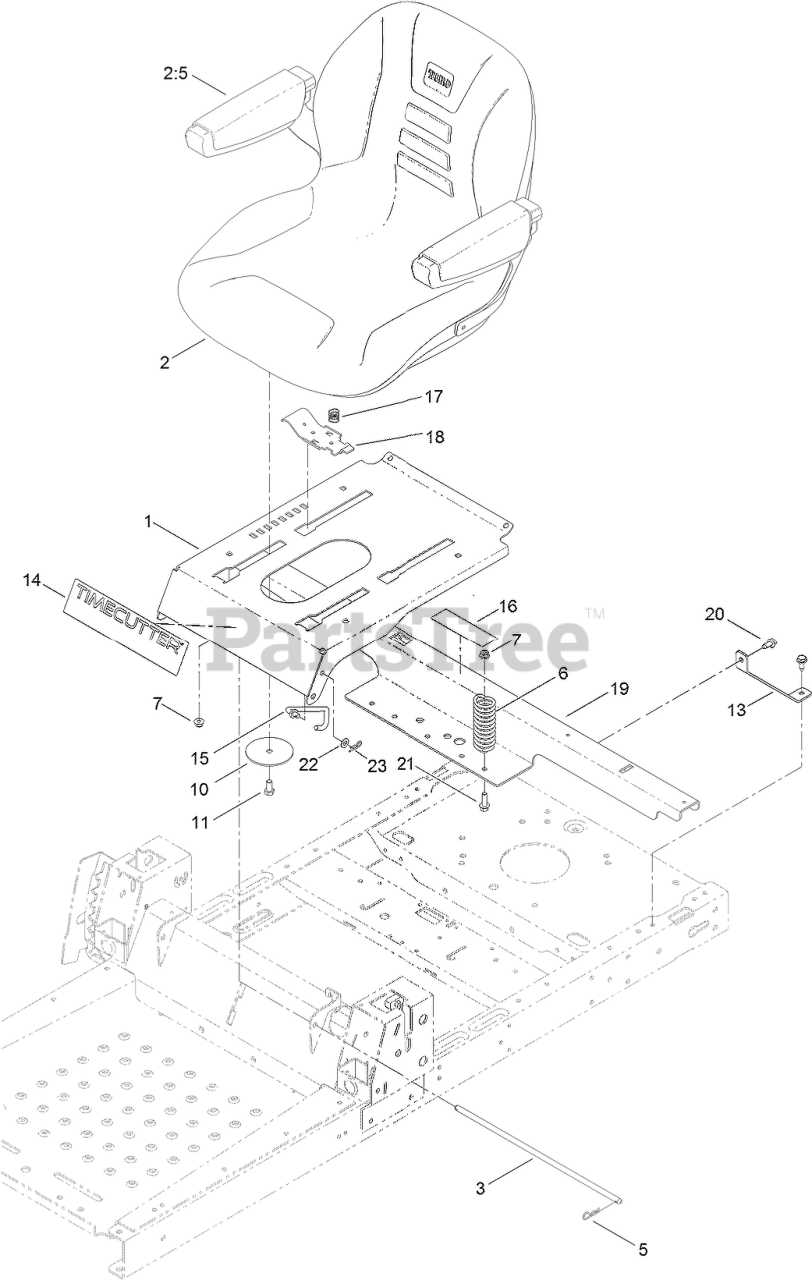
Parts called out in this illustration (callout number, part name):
1	PAN-SEAT
2	18 INCH SEAT ASM
2:5	ARMREST KIT
3	ROD-STOP
5	PIN-COTTER
6	SPRING-COMPRESSION
7	NUT-HF, NI
10	WASHER-SEAT
11	SCREW-HH
13	SUPPORT-TANK, REAR
14	DECAL-TIMECUTTER
15	STOP-SEAT
16	DECAL-SERVICE, CE
17	SPRING-COMPRESSION
18	LATCH-SEAT
19	SUPPORT-POD
20	SCREW-HWHTF
21	SCREW-HHF
22	WASHER-PLAIN
23	PIN-COTTER
